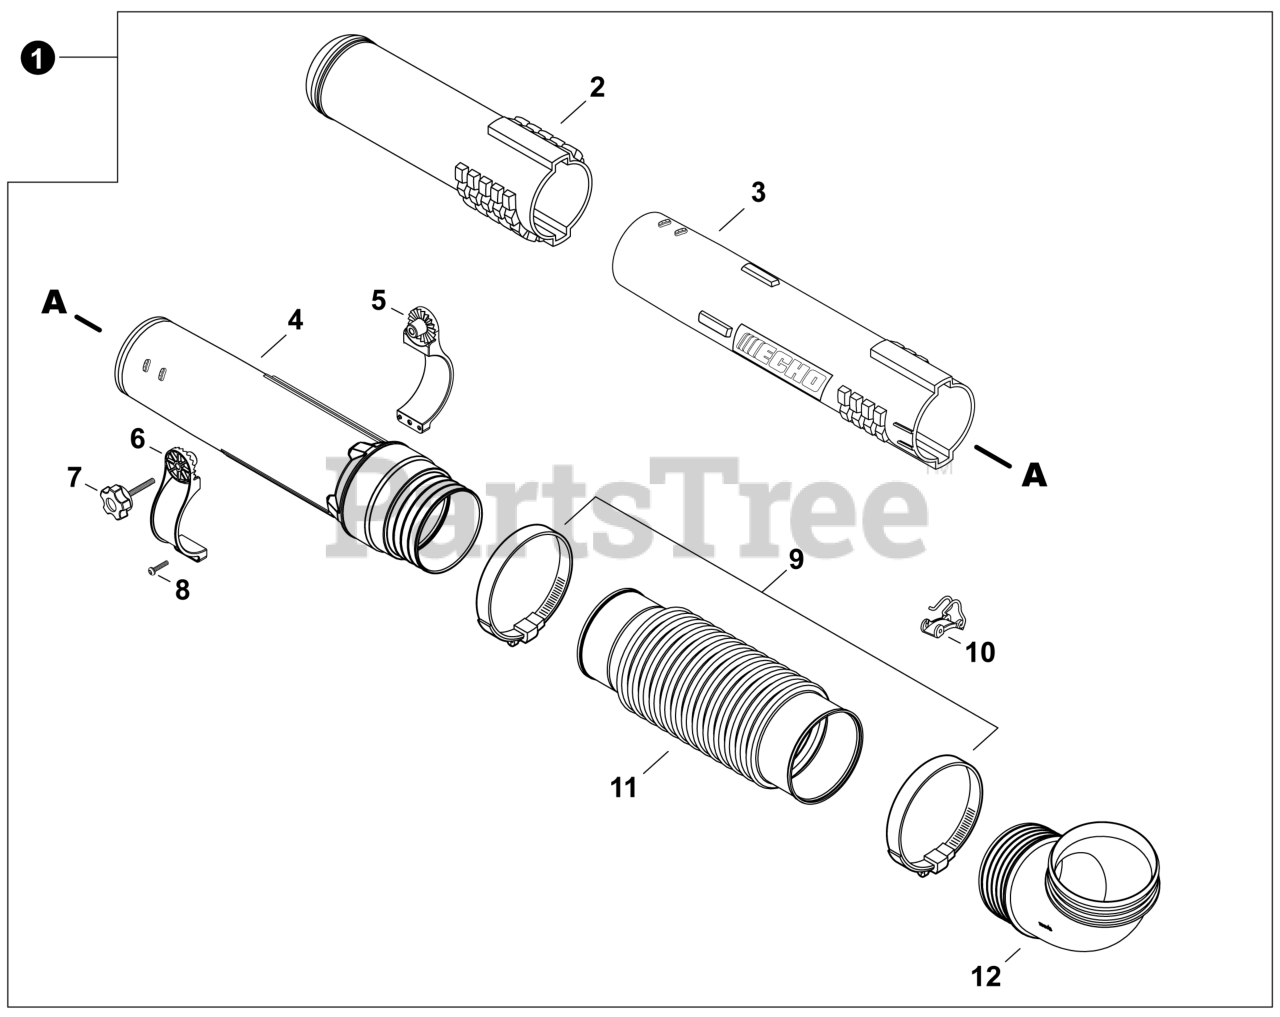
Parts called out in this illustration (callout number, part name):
1	TUBE KIT, BLOWER, TUBE MOUNT
2	TUBE, BLOWER - NOZZLE
3	TUBE, BLOWER - STRAIGHT
4	TUBE, BLOWER - SWIVEL
5	BRACKET, RIGHT
6	BRACKET, LEFT
7	KNOB, SCREW
8	BOLT, TORX 5x20
9	CLAMP - BAND 77.8 MM / 101.6 MM
10	CLIP, CABLE
11	TUBE, BLOWER - FLEXIBLE
12	TUBE, BLOWER - ELBOW
